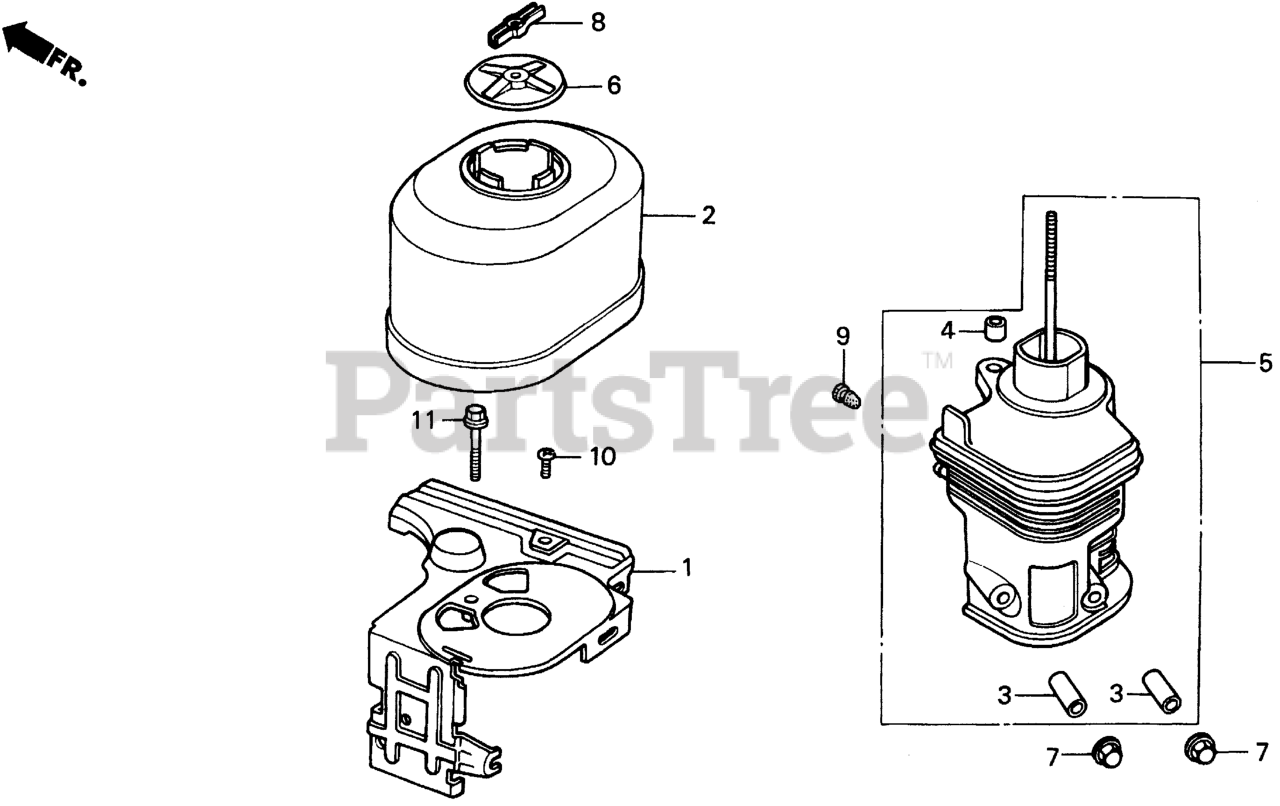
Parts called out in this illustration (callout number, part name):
1	COVER, CONTROL
2	COVER, AIR CLEANER (SEMI-DRY)
3	COLLAR, AIR CLEANER
4	COLLAR B, AIR CLEANER
5	ELBOW, AIR CLEANER
6	CAP, AIR CLEANER
7	NUT, CAP (6MM)
8	WINGNUT, AIR CLEANER COVER
9	PLUG, CONE TYPE
10	SCREW, PAN (6X8)
11	BOLT, FLANGE (8X35)
